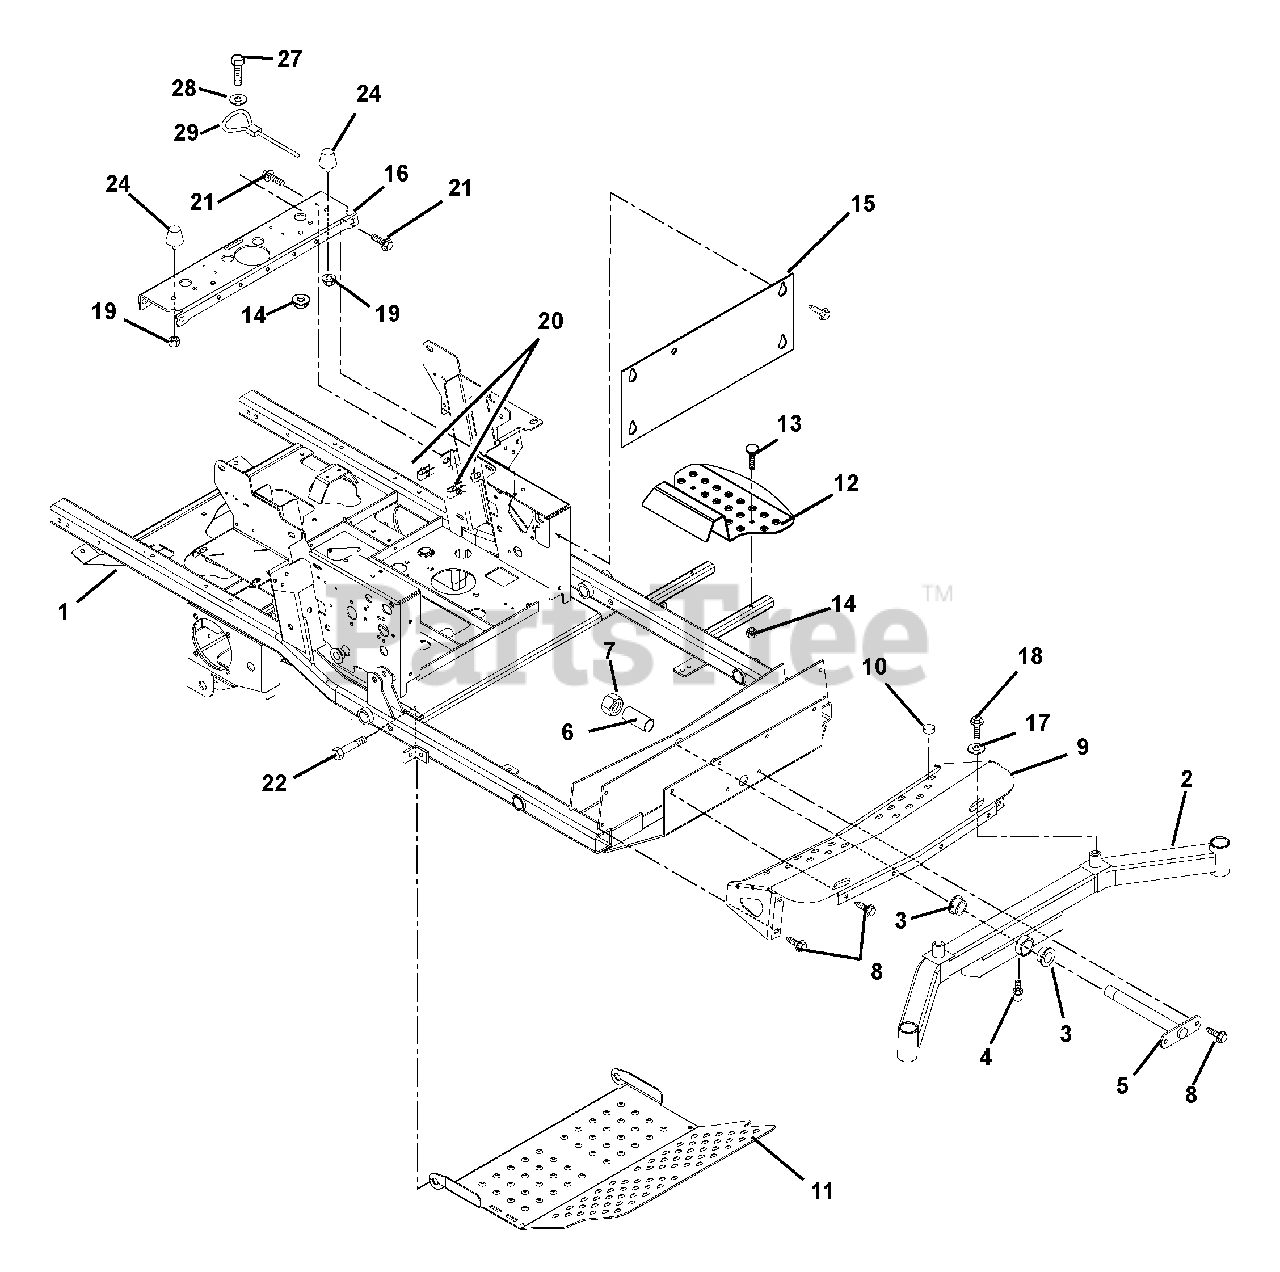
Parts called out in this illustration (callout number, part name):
1	Weldment, Frame
2	Weldment, Axle
3	Bushing, Flange 1.02 x 1.385 x .75 x 1.75
4	Fitting, Lube .25-28 x .256
5	Pin, Axle
7	Nut, Locking Nylon 1.00-14
8	Screw, Tapping .38-16 x .75
9	Weldment, Axle Cover
10	Button, Bumper
11	Panel, Inspection
12	Step, Ingress
13	Bolt, Round Head Square Neck .31-18 x 1.75 Grade 5
14	Nut, Locking Top Flange .31-18
15	Plate, Kick
16	Channel, Cross
17	Washer, Flat Steel .640 x 1.81 x .25
18	Bolt, Hex .50-20 x 1.00 Grade 5
19	Nut, Locking Flange .312-24
20	Nut, Retainer .375-16 x .37
21	Bolt, Serrated Hex Flange Washer Head .38-16 x 1.00
22	Bolt, Hex .50-13 x 3.25 Grade 5
23	Washer, Flat Steel .563 x 1.38 x .109
25	Nut-Locking-Top-Flange .50-13
26	Bushing, Flange .515 x .75 x .275 x 1.12
27	Bolt, Hex .31-18 x .75 Grade 5
28	Washer, Flat Steel .328 x 1.00 x .094
29	Cable, Seat Prop.
